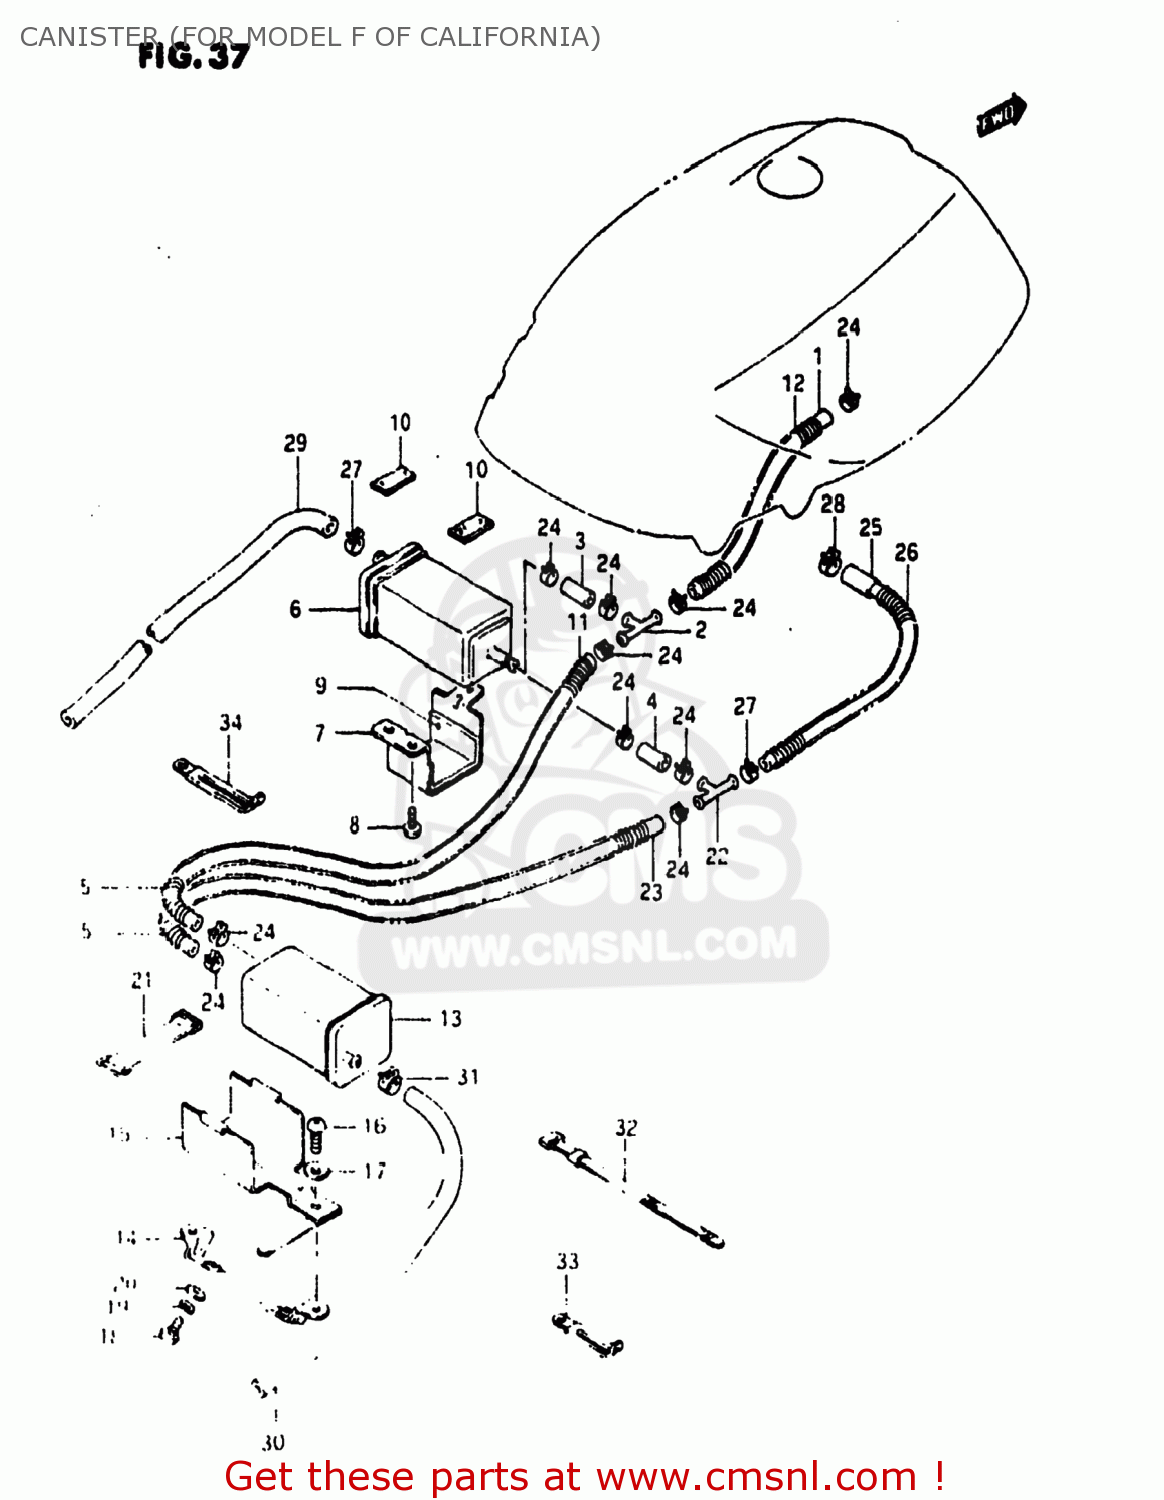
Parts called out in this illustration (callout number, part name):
1	HOSE
2	PIPE
3	HOSE
4	HOSE
5	(CA) SPRING
6	(CA) CANISTER ASSEMBLY
7	BRACKET,CANISTER
8	SCREW
9	CUSHION, CANISTER NO. 1
10	CUSHION,CANISTER
11	HOSE
12	SPRING
13	(CA) CANISTER ASSEMBLY
14	BRACKET,CANISTER PURGE
15	PLATE,CANISTER
16	SCREW
17	WASHER, LOWER
18	SCREW
19	WASHER,LOCK
20	WASHER
21	BAND
22	PIPE CANISTER
23	HOSE
24	CLIP
25	HOSE
26	SPRING
27	CLIP
28	CLIP
29	HOSE
30	HOSE
31	CLIP
32	CLAMP(L:187)
33	CLAMP
34	CLAMP
